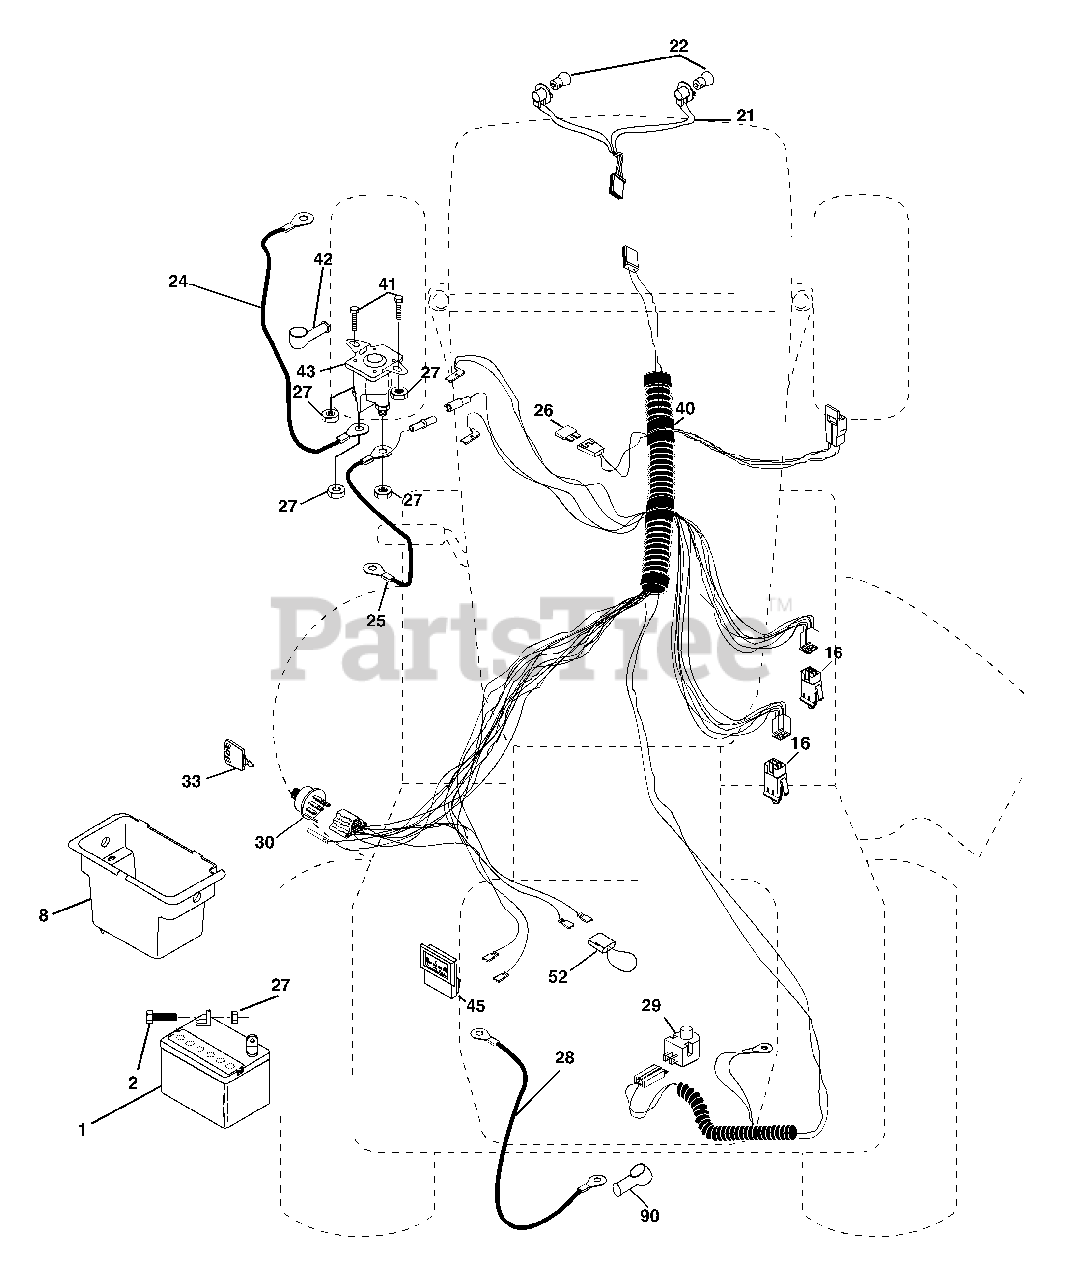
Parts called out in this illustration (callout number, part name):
1	Battery 12 Volt 25 Amp
2	Bolt Hex Hd 1/4-20 unc x 3/4
8	Box Battery
16	Switch Interlock Push -In
21	Harness Asm Light W/4152J
22	Bulb Light #1156
24	Cable Battery 6 Ga. 11" red
25	Cable Battery 6 Ga. w/16 wire,red
26	Fuse 20 AMP
27	Nut Keps Hex 1/4-20 unc
28	Cable Ground 6 Ga. 12" black
29	Switch Plunger Nc Gray
30	Switch Ign
33	Key Ign
40	Harness Ign
41	Bolt Blk Fin Hex 1/4-20 x 1/2
42	Cover Terminal Red
43	Solenoid
45	Ammeter
52	Protection Wire Loop
90	Cover Terminal
